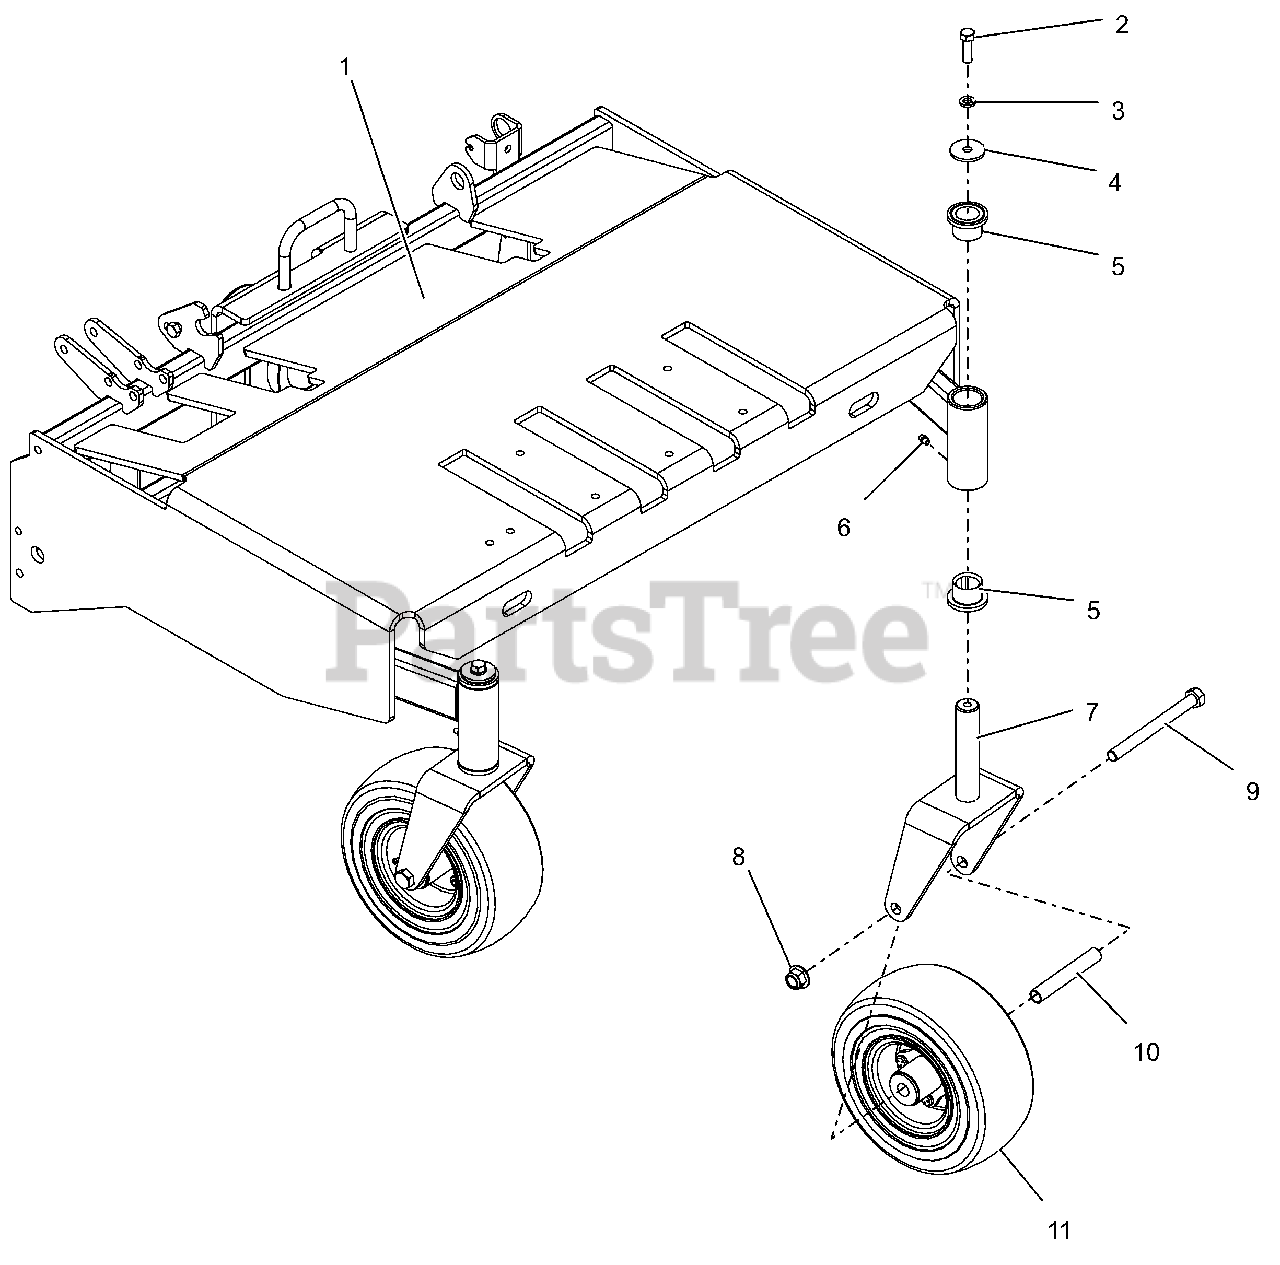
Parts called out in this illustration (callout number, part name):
1	WLDMT, FRAME
2	BLT, HEX .38-16X1.25 G5 ZCC
3	WSHR,LK-REG .375X.094 ZCC
4	WSHR, FLT .380X1.50X.125 ZCC
5	BRG, FLG 1.00 X 1.25 X 1.00
6	FTG-LUBE .25-28X.256 SST
7	WLDT, FRONT WHEEL FLWLK GRVLY
8	NUT,NYL-FLG .50-13 GF ZCC
9	BLT,HEX .50-13X5.50 G5 ZCC
10	TUBE, CASTER AXLE
11	ASSM TIRE\WHEEL, 9 x 3.50-4
